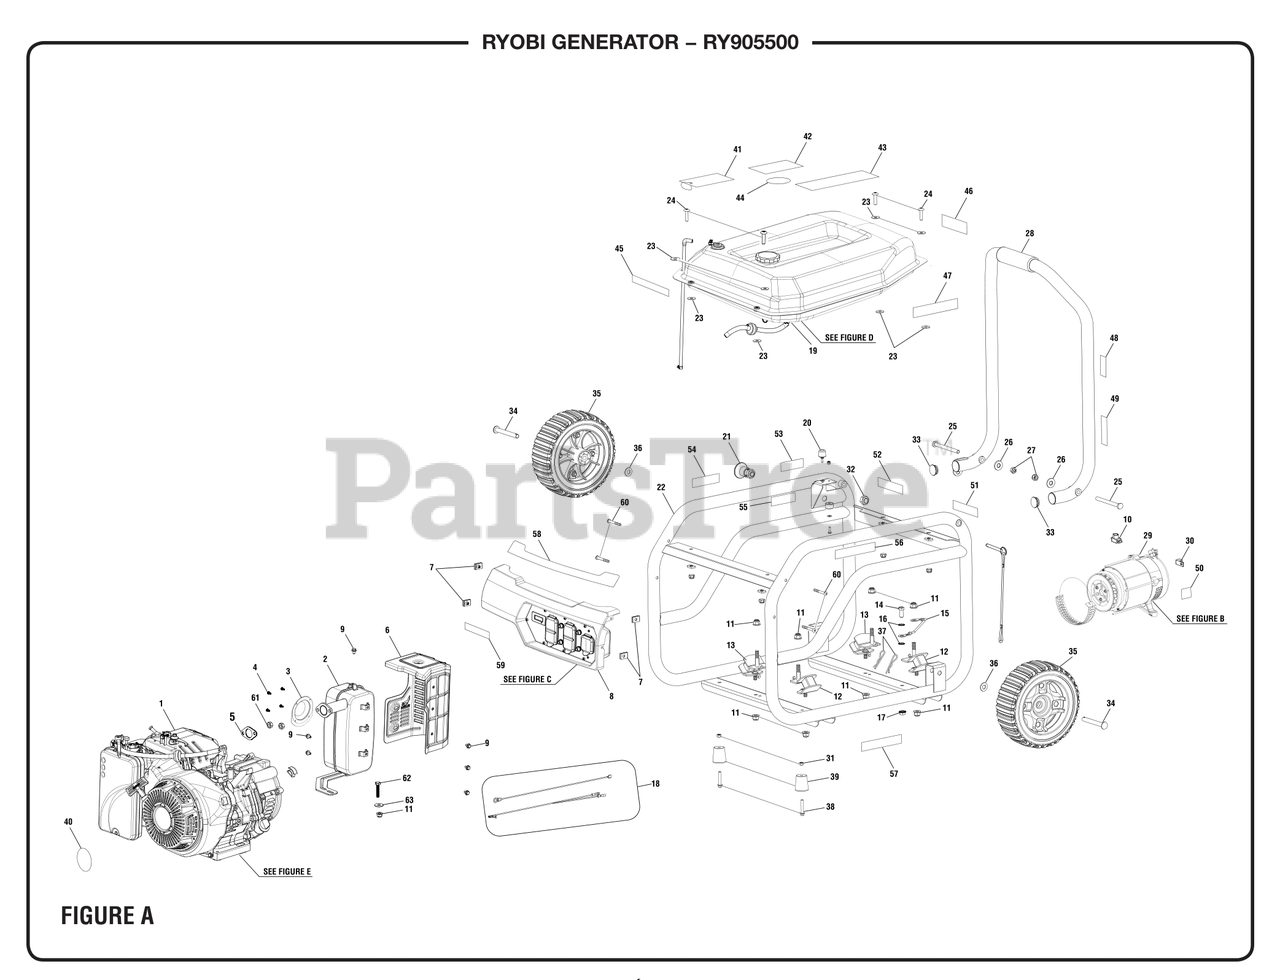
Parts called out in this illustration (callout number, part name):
1	Engine (Subaru EA190)
3	Spark Arrester
4	Screw (8-32 x 3/8 in.)
5	Exhaust Gasket
6	Heat Shield
7	U-Clip (M6)
8	Control Panel Assembly
9	Bolt (M6 x 9 mm, Hex Flange Hd.)
10	Rubber Wire Protector
11	Lock Nut (M8)
12	Isolator (Large)
13	Isolator (Small)
14	Bolt (5/16-18 X 0.75 in.)
15	Ground Wire Assembly
16	Star Washer (5/16 in.)
17	Flange Nut (5/16-18)
18	Wire Assembly
19	Fuel System
20	Handle Bumper
21	Quick Release Pin
22	Carrier Assembly
23	Washer (1/4 in., Type A)
24	Screw (1/4-20 x 1 in., T30 Torx Hd.)
25	Handle Pivot Bolt
26	Washer (5/16 in.)
27	Lock Nut (5/16-18)
28	Handle Assembly
29	Generator Head Assembly
30	Ground Lug
31	Lock Nut (M8)
32	Lock Nut (1/2-20)
34	Axle Bolt
36	Washer (M10)
37	Hitch Pin
38	Bolt(M8 x 45 mm, Hex Flange Hd.)
40	Recoil Label
41	Notice Hangtag
42	Warning Label
43	CPSC Label
44	Fuel Stabilizer Label
45	Logo Label
46	Combustion Warning Label
47	Start Label
48	Fuel Stabilizer Label (SP/FR)
49	E85 Label
50	Ground Label
51	Ground Warning Label
52	Fire Danger Label
53	Pin Release Label
54	Inquiries Label
55	Hot Surface Label
56	Fire Distance Label
57	Lubricant Label
58	Performance Label
59	Choke Label
60	Screw (M6 x 50 mm, T30 Torx Pan Hd. )
61	Hex Nut (M8 x 1.25, Special)
62	Screw (M8 x 40 mm, Hex Hd.)
63	Washer (ID9 x OD25.4 x 2t)
